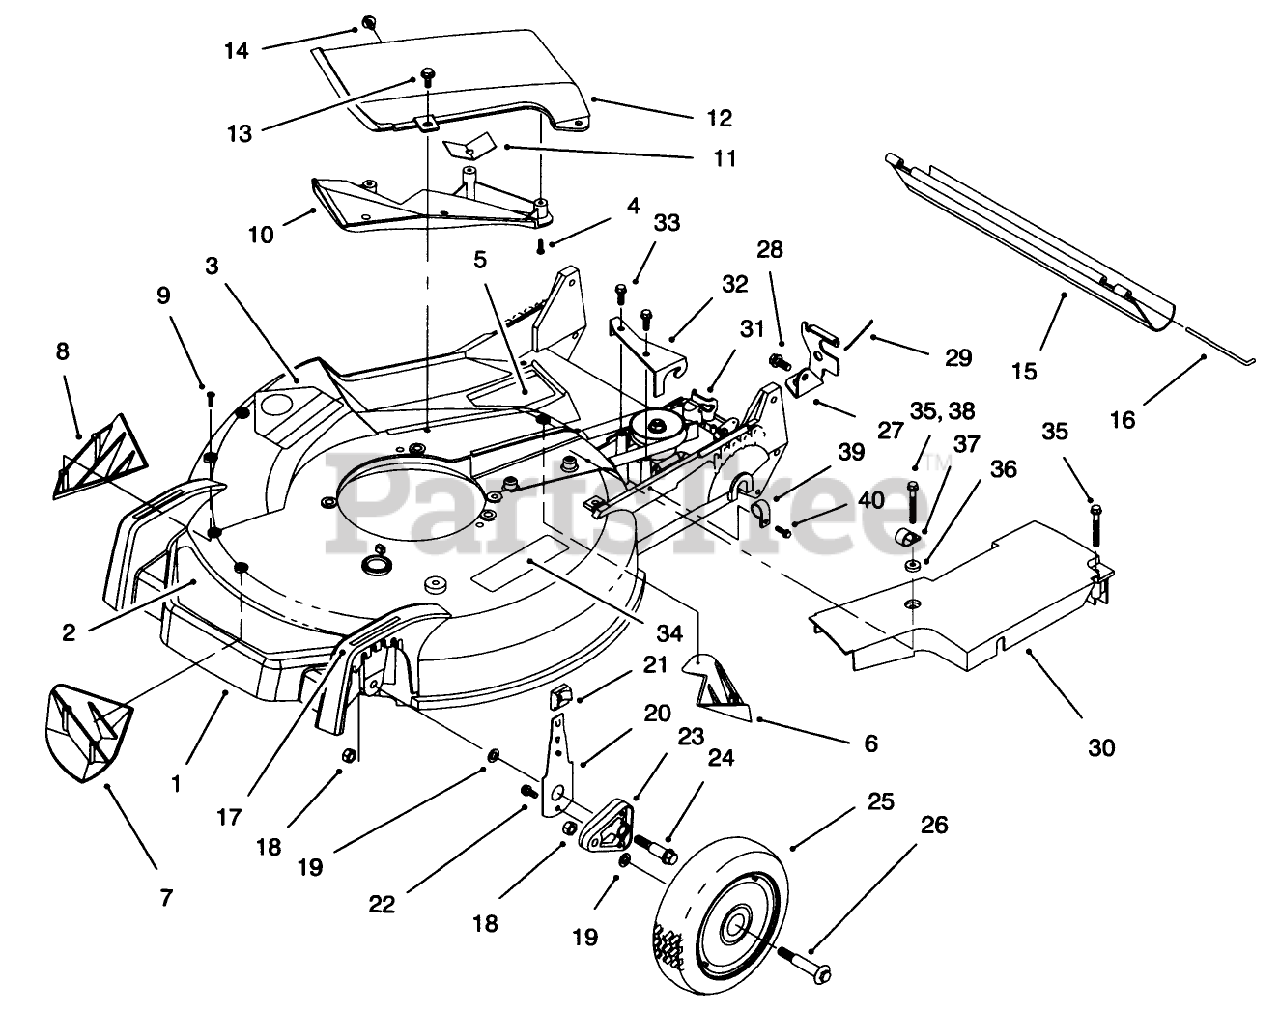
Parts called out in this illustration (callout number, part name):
2	DECAL - DECK
3	DECAL-DANGER
4	Screw-PPH
5	DECAL - DANGER
6	KICKER-REAR
7	KICKER-FRONT
8	KICKER-RH
9	SCREW-PPH
10	Deflector-Recycler
11	Guard-Cover
13	SCREW-HWH
14	SCREW AND WASHER ASM
16	ROD-SHIELD
18	NUT-LOCK
19	WASHER
20	FRONT SPRING ARM ASM
21	KNOB-ARM
22	SCREW-HWH
23	ARM-PIVOT, FRONT
24	BOLT-SHOULDER
25	WHEEL AND TIRE ASM
28	SCREW-HWHTF
29	RETAINER-CABLE
30	COVER - BELT
31	GEARCASE ASM
33	SCREW-HWHTF
35	SCREW-HWH
36	WASHER
37	CLAMP-CABLE
38	SCREW-SPECIAL
39	CLAMP-CABLE
40	SCREW-HWH
